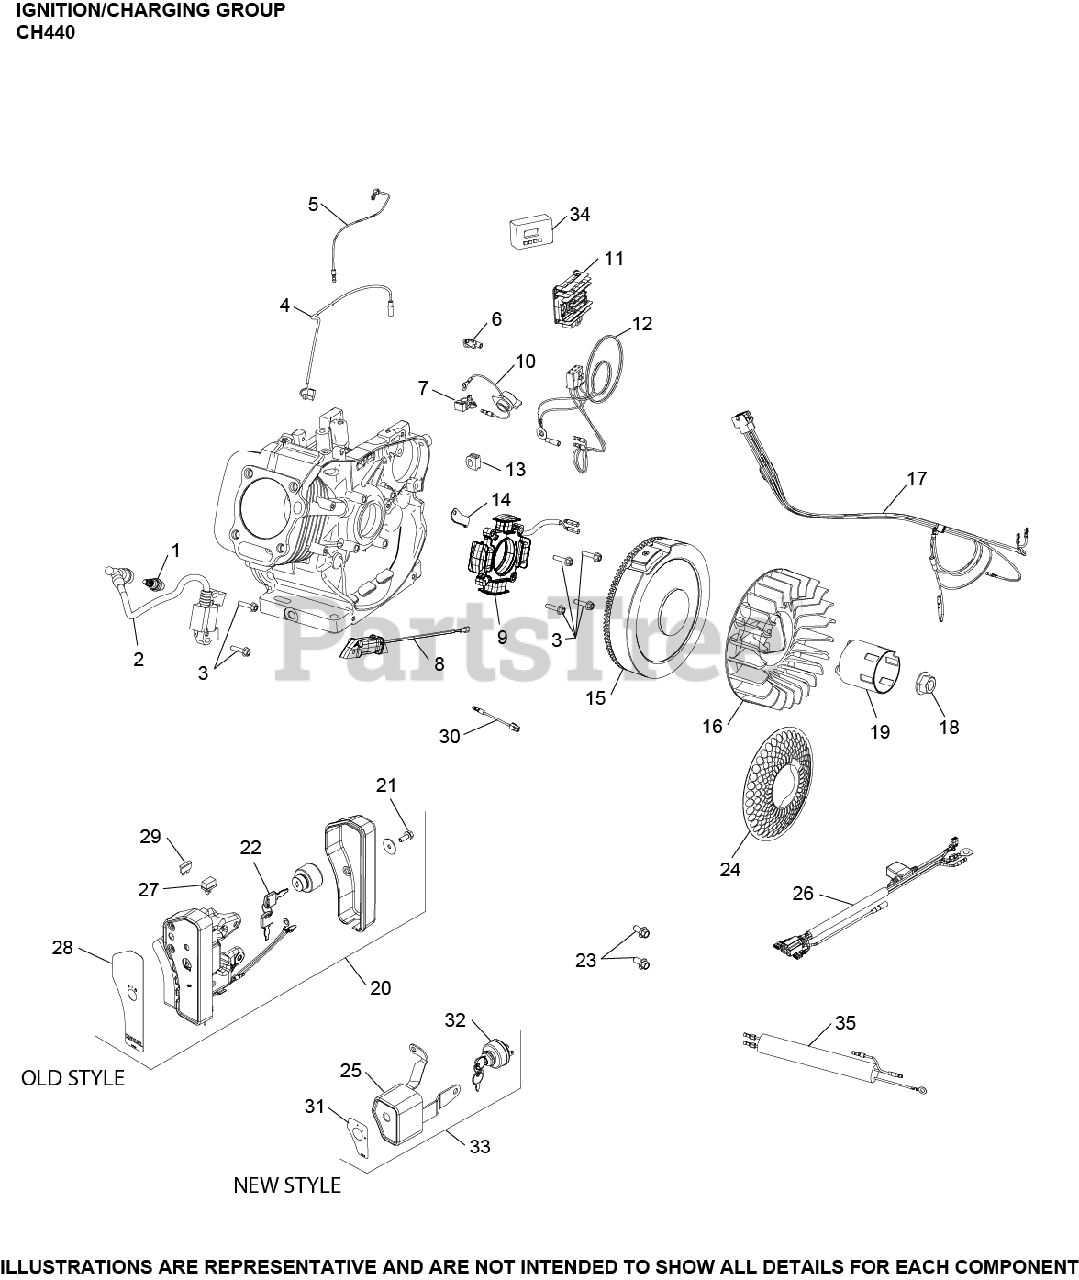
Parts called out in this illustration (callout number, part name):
1	SPARK PLUG, RFI
2	MODULE, IGNITION
3	SCREW, M6 X 25 USE 25 086 436-S
4	LEAD, GROUND TO KILL
9	STATOR ASSEMBLY, 3 POLE
11	REGULATOR, 10 AMP
12	HARNESS, REGULATOR WIRING ASSY
14	BRACKET, STATOR WIRE
15	FLYWHEEL,ASSY ELECT.STRT 10/18AMP
16	FAN, FLYWHEEL
18	NUT, FLYWHEEL
19	CUP, STARTER DRIVE
20	KEY BOX ASSY W/HARNESS AND SWITCH
21	SCREW, HEX FLANGE (M6)-USE 25 086 433-S
22	KEYS FOR SWITCH
25	KEYBOX HOUSING ASSEMBLY
28	LABEL, ELECTRIC BOX
31	LABEL, KEY BOX
32	SWITCH, KEY ASSEMBLY USE 25 099 37-S
33	KIT, KEY BOX ASSEMBLY
